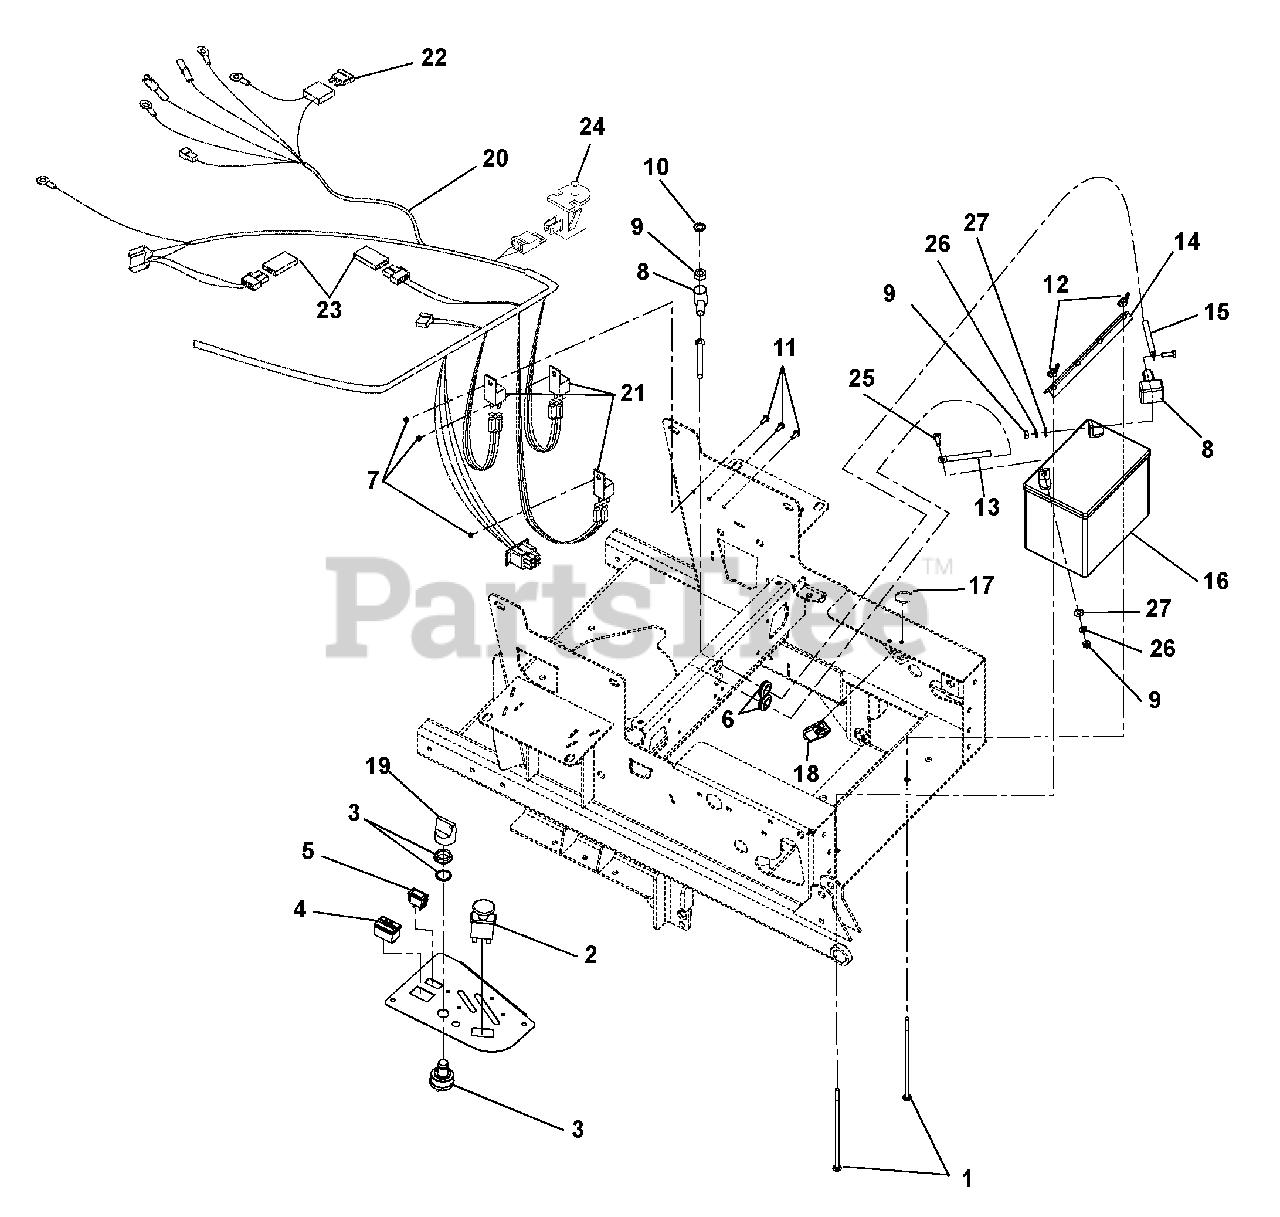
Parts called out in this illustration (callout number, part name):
1	Bolt, Round Head Square Neck .25-20 x 7.50
2	Switch, Clutch
3	Switch, Ignition
4	Hour Meter- Digital
5	Light, Indicator
6	Grommet, Rubber 5/8 ID/1.13
7	Nut, Locking-Nylon 10-24 with Insert
8	Boot, Eyelet Terminal
9	Nut, Hex .25-20
10	Washer, Locking-EXT.262 x .502 x .026
11	Screw, Machine 10-24 x .50 Hex Washer Head
12	Nut, Locking Wing .250-20
13	Ground Cable .31 x 22.00 x .31
14	Hold Down
15	Cable, Positive Battery 26.00"
16	Exide Battery Sealed Maintenance Free U1-250
17	Cable Tie
18	Switch, Snap In- N.O./N.O.
19	Key, with Shield
20	Harness, Wire- IZ, CZ, 100I
21	Relay,Sealed w/Diode
22	Fuse, 30 AMP.
23	Diode, Connector Shell
24	Switch, Snap Mounting (N.O.)
25	Bolt, Hex .25-20 x .75 Grade 5
26	Washer, Locking .25 x .062 Regular
27	Washer, Flat-STL.281 x .62 x .065
